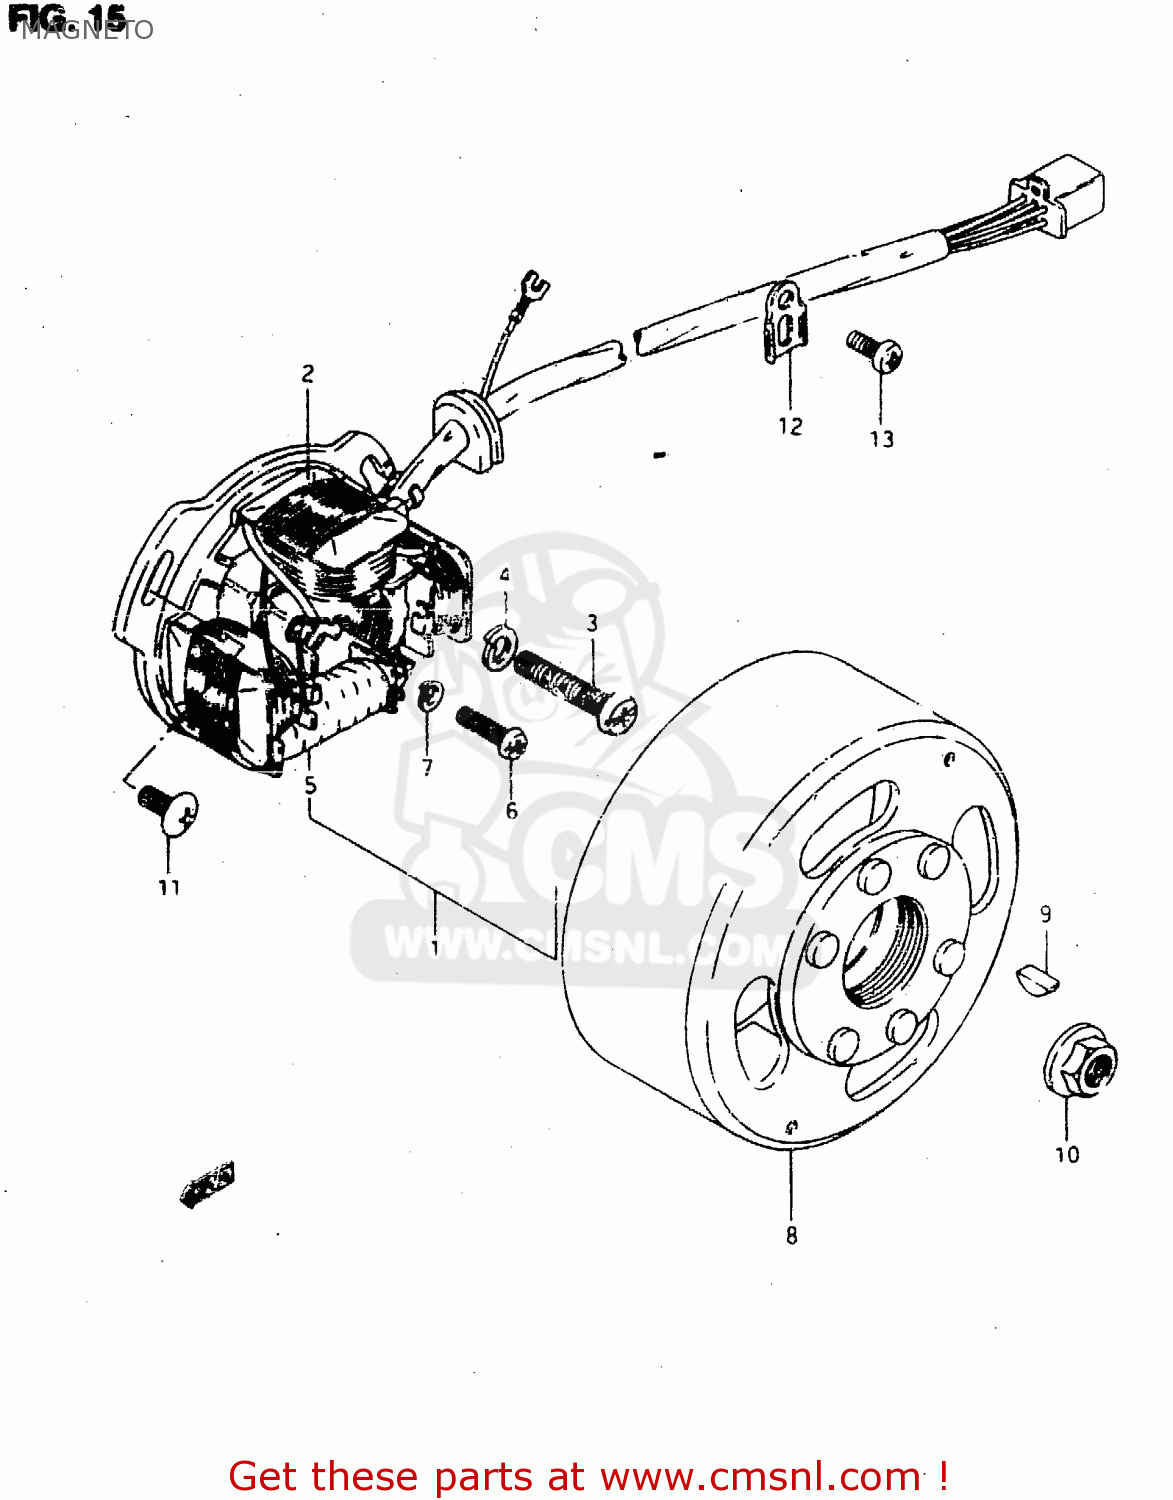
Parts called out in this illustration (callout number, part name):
1	STATOR ASSY
2	COIL,STARTER
3	SCREW
4	WASHER,LOCK
5	COIL,PRIMARY
6	SCREW 4X16
7	WASHER,LOCK
8	ROTOR
9	KEY
10	NUT
11	SCREW
12	CLAMP,GENERATOR LEAD WIRE
13	SCREW
